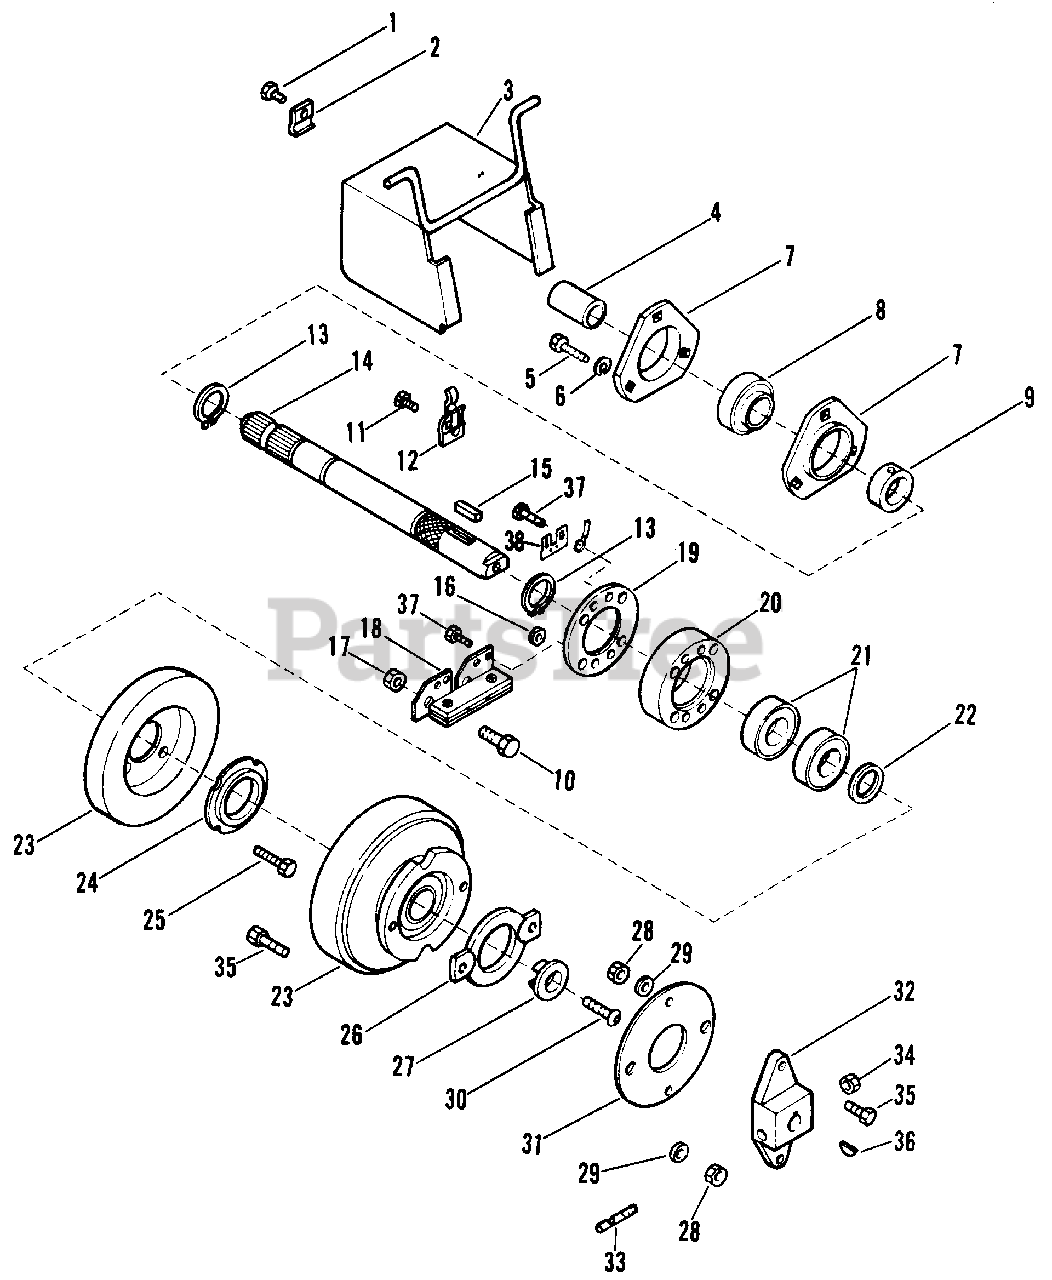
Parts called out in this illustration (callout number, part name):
1	Taptite, 1/4-20 x .50
2	Clip
3	PTO Shield
4	Shaft Cover
5	Bolt, Hex 5/16-18 x .75
6	Washer, Lock 5/16 SP
7	Bearing Flange
8	Ball Bearing, 1" I.D. x 2-3/64 O.D.
9	Bearing Collar
10	Bolt, Hex 5/16-18 x 1.50
11	Screw, Taptite #10-24 x .375
12	Snap Fastener
13	Ring, Retaining
14	Shaft
15	Key, Square .25 x 1.00
16	Nut, Torque Lock #10-24 Gr A
17	Nut, Lock 5/16-24
19	Ring
20	Bearing Mount
21	Bearing, Ball
22	Washer, 1.031/1.046 x 1.375 x .055
23	Electric Clutch
24	Bearing Flange
25	Screw, Mach. No. 10-24 x 1.25 Pan
26	Pilot Plate
27	Retainer
28	Nut, Lock 5/16-18
29	Washer, Flat .375 x .734 x .065
30	Screw, Cap BTHD 3/8-16 x 1.25
31	Spacer, Coupling
32	Coupling
33	Lock Stud
34	Nut, Lock 3/8-16
35	Bolt, Hex 5/16-18 x .875
36	Key, Woodruff .187 x .75 #9
37	Taptite #10-24 x .75
38	Clip, Connector Mounting
NS	Rear PTO Decal, 3200 RPM
